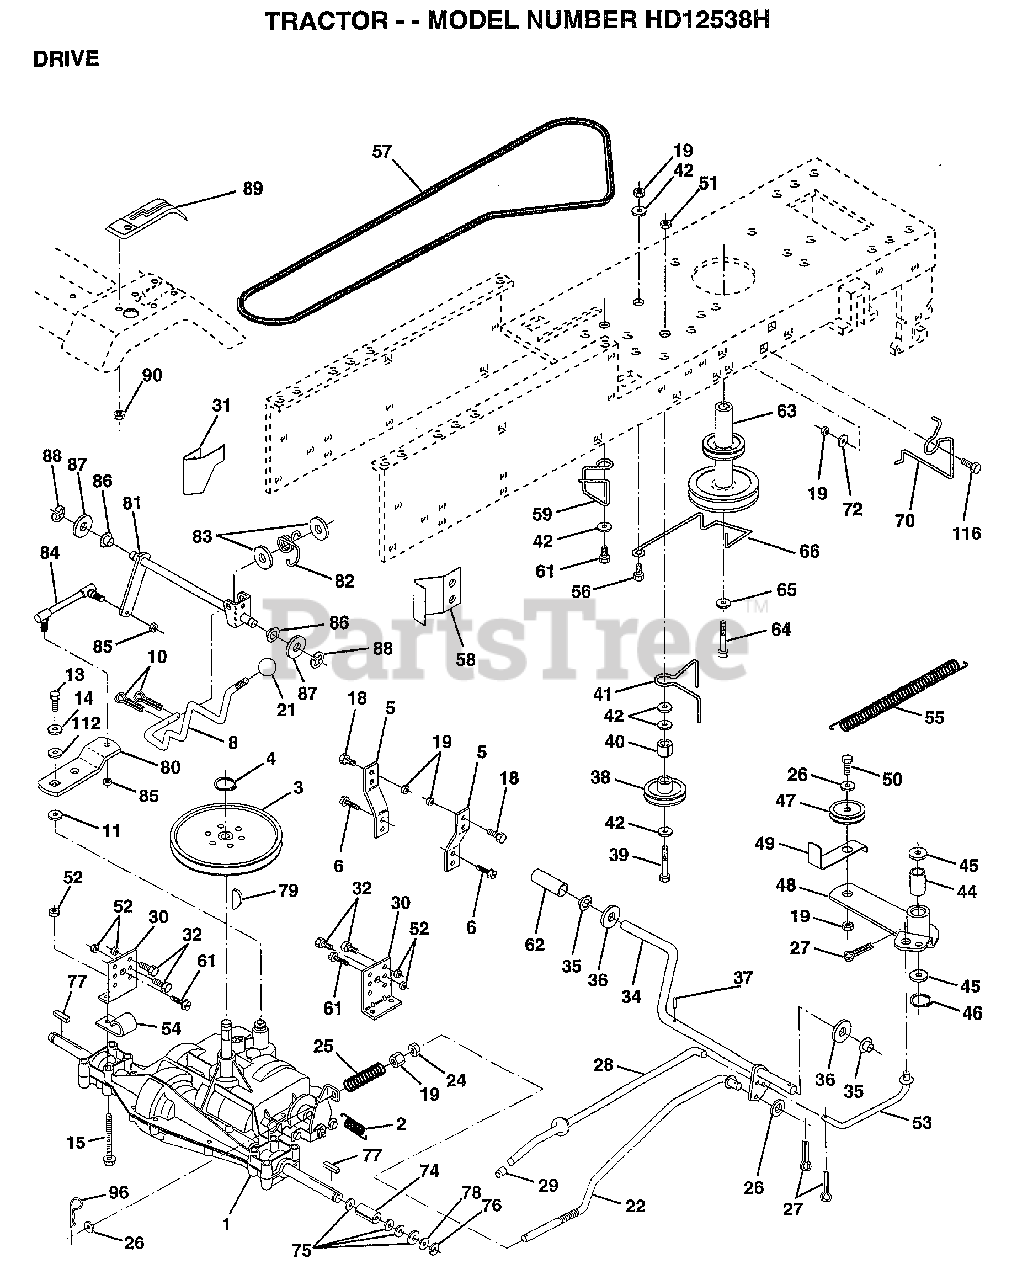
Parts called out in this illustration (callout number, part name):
2	SPRING.BRAKE.RETU
3	PULLEY TRANS
5	STRAP TORQUE
6	SCREW
7	BRKT.SADDLE.SHIFT
8	SHIFT ROD
10	PIN COTTER 1/8
11	WASH-SHFT PLT LT
12	WASHER
13	BOLT.1/4-28.W/PAT
14	LOCKWASHER
18	BOLT
19	NUT
21	KNOB T (1/2-HOLE)
22	BRAKE ROD
24	NUT
25	SPRING ROD LT
26	WASHER
27	COTTER PIN
28	ROD.BRAKE.PARK.LT
29	PLUNGER CAP T
30	TRANSAXLE MTG BKT
31	"KEEPER,BELT LH T"
32	BOLT
34	SHAFT ASM-PEDAL F
35	NYLON BEARING
36	WASHER LT
38	PULLEY.IDLER.FLAT
39	BOLT
40	SPACER T
42	WASHER
48	BELLCRANK.CLUTCH
49	RETAIN BELT
53	"LINK, CLUTCH T"
54	CLIP T
55	"SPRING, RETURN LT"
58	"KEEPER,BELT RH T"
59	KEEPER BELT CNTSP
61	SCREW
62	PEDAL COVER T
63	PULLEY.ENGINE
64	BOLT
65	LOCKWASHER
66	KEEPER-BELT
70	KEEPER BELT ENG
72	WASHER
74	SPACER AXLE
75	WASHER
76	E-RING LT
77	SQUARE KEY
78	WASHER
96	RETAINER M
112	WASHER LT
113	"STRAP,TORQUE"
116	BOLT RDHD 3/8-16
145	BOLT.HEX.FLGHD
149	SPACER RETAINER
150	BUSHING.NYLON
151	WASHER
